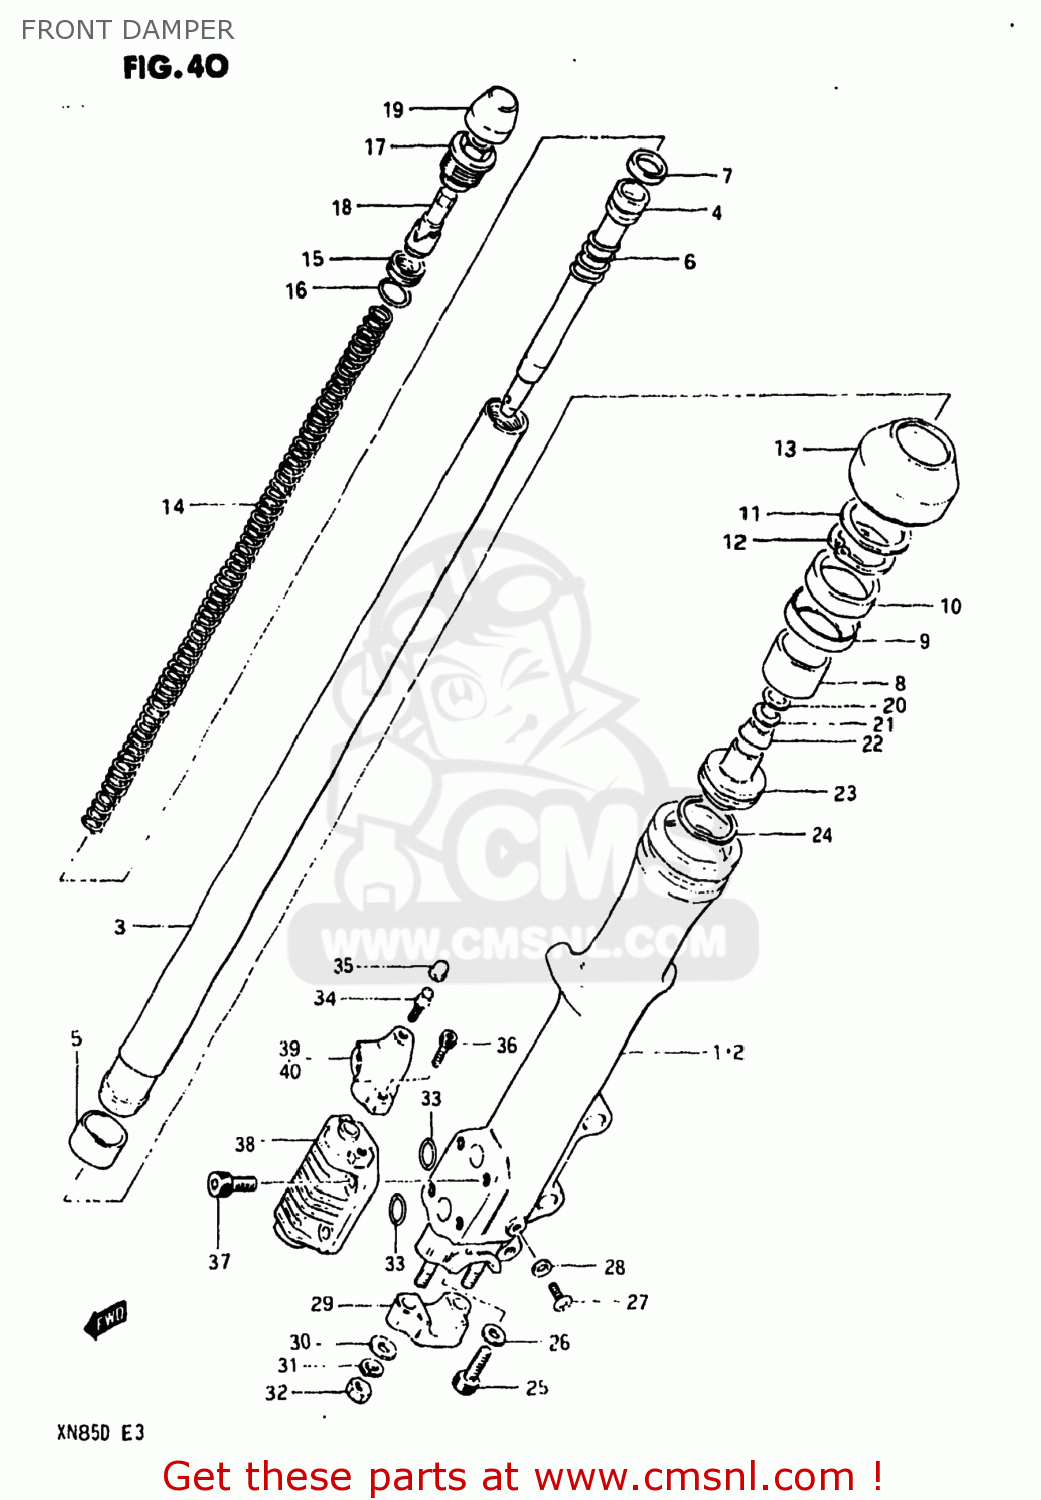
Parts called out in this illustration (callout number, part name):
0	DAMPER ASSEMBLY,LEFT
1	TUBE,OUTER,RIGHT
2	TUBE,FORK,LEFT,OUTER
3	TUBE,FORK,INNER
4	CYLINDER,FRONT FORK
5	PISTON
6	SPRING REBOUND
7	RING,PISTON
8	GUIDE,FORK INNER TUBE
9	SPACER,SEAL
10	OIL SEAL,FRONT FORK
11	RING,BACKUP
12	CIRCLIP,INNTERNAL
13	BOOT
14	SPRING,FRONT
15	SEAT,FRONT FORK SPRING
16	O RING
17	CAP,FORK INNER TUBE
18	ADJUSTER,SPRING
19	CAP
20	VALVE
21	SPRING,VALVE
22	VALVE,OIL LOCK PIEACE
23	PIECE,OIL LOCK
24	RING,PISTON
25	BOLT(8X27)
26	GASKET (NAS)
27	SCREW 4X6
28	GASKET (NAS)
29	HOLDER,AXLE
30	WASHER
31	LOCK WASHER
32	NUT
33	O RING,FR FORK
34	BREATHER
35	CAP
36	BOLT
37	BOLT
38	MODULATOR PLANGER SET
39	MODULATOR PLANGER SET
40	MODULATOR PLANGER SET
